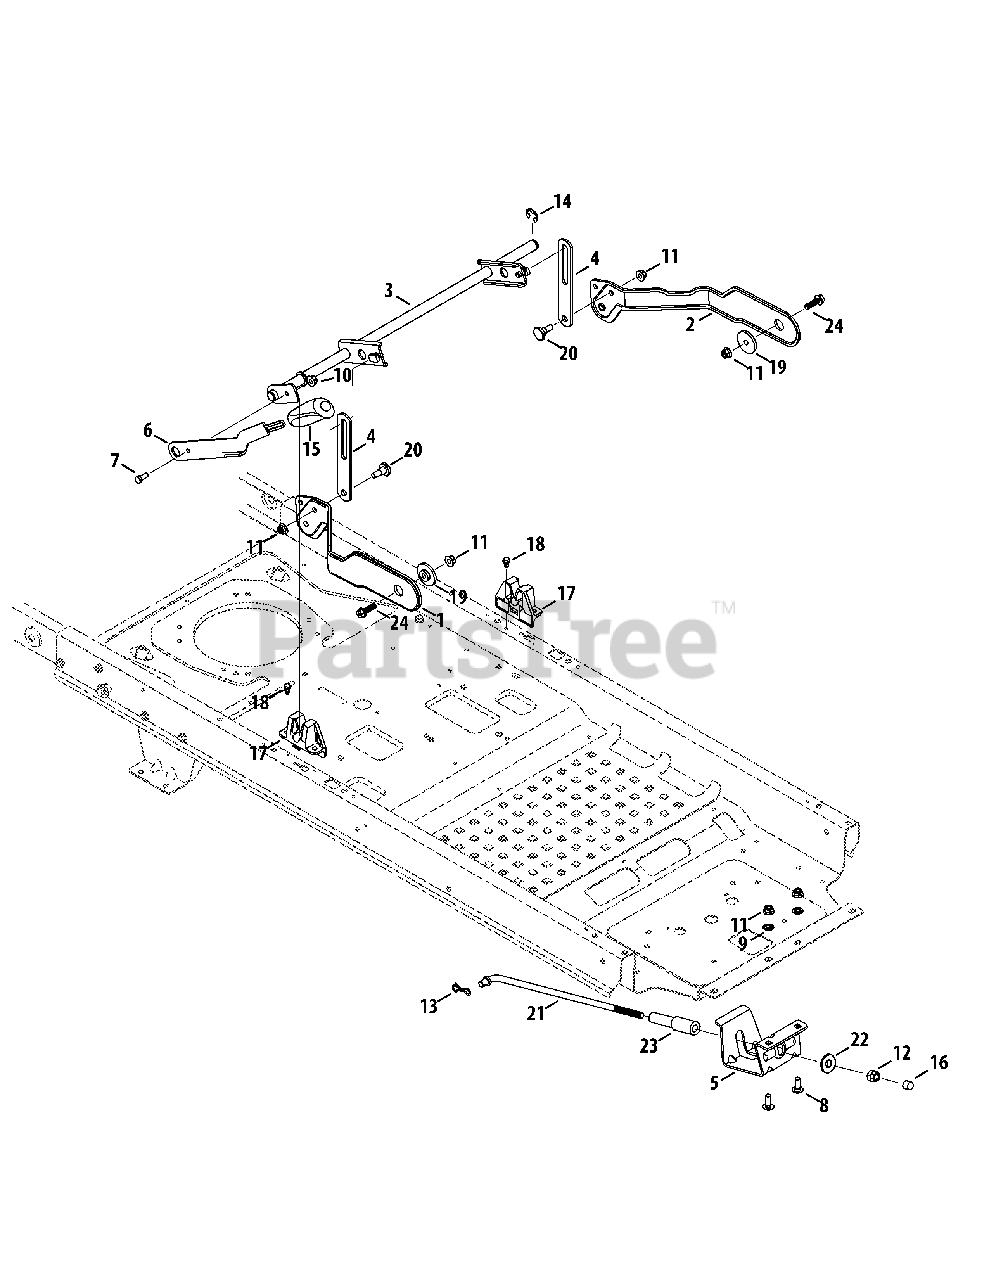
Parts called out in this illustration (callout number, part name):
1	Deck Lift Plate, RH
2	Deck Lift Plate, LH
3	Deck Lift Shift Assembly
4	Lift Link Plate
5	Rod Support Mounting Bracket
6	Deck Lift Handle
7	Hex Cap Screw, 5/16-18 x .75
8	Carriage Bolt, 3/8-16 x 1.00
9	Push Nut, 3/8
10	Flange Lock Nut, 5/16-18
11	Flange Lock Nut, 3/8-16
12	Hex Nut, 1/2-13
13	Bow-Tie Cotter Pin
14	E-Type Ring, .750
15	Grip, .50 ID
16	End Cap
17	Deck Lift Bracket
18	Shoulder Screw, .500 x 1/4-20
19	Shoulder Spacer, .854 x .232
20	Shoulder Screw, .500 Dia. x .434
21	Deck Lift Rod
22	Deck Lift pivot Cup
23	Nylon Sleeve, .55 ID x 4.50 LG
24	Screw, 3/8-16 x 1.00
